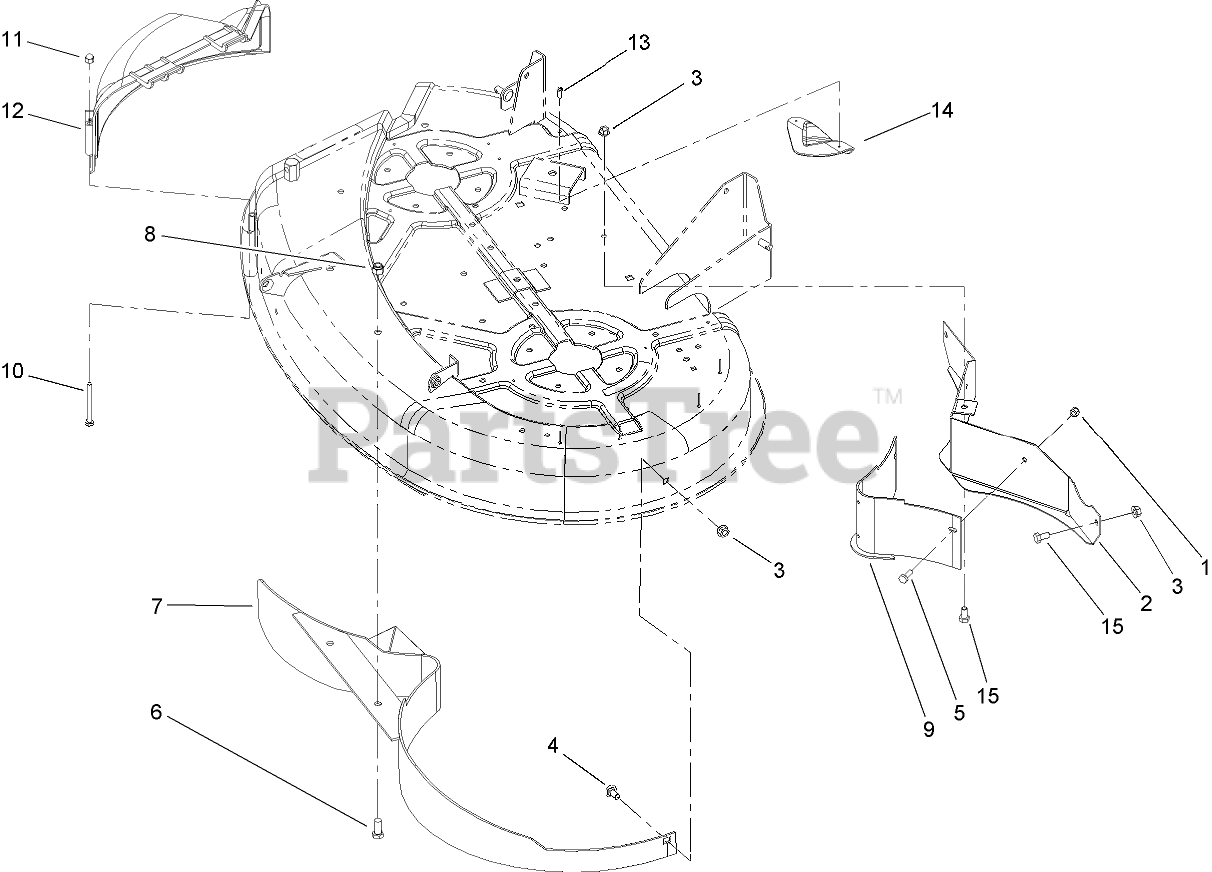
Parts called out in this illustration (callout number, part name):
1	NUT-LOCK, NI
2	BAFFLE-REAR
3	NUT-HF
4	BOLT-CARR
5	SCREW-HH
6	SCREW-HH
7	BAFFLE ASM
8	NUT-LOCK, NI
9	BAFFLE ASM
10	SCREW-HH
11	NUT-CAP
12	COVER-RECYCLER
13	SCREW-PPH
14	PLATE-KICKER
15	SCREW-HH
